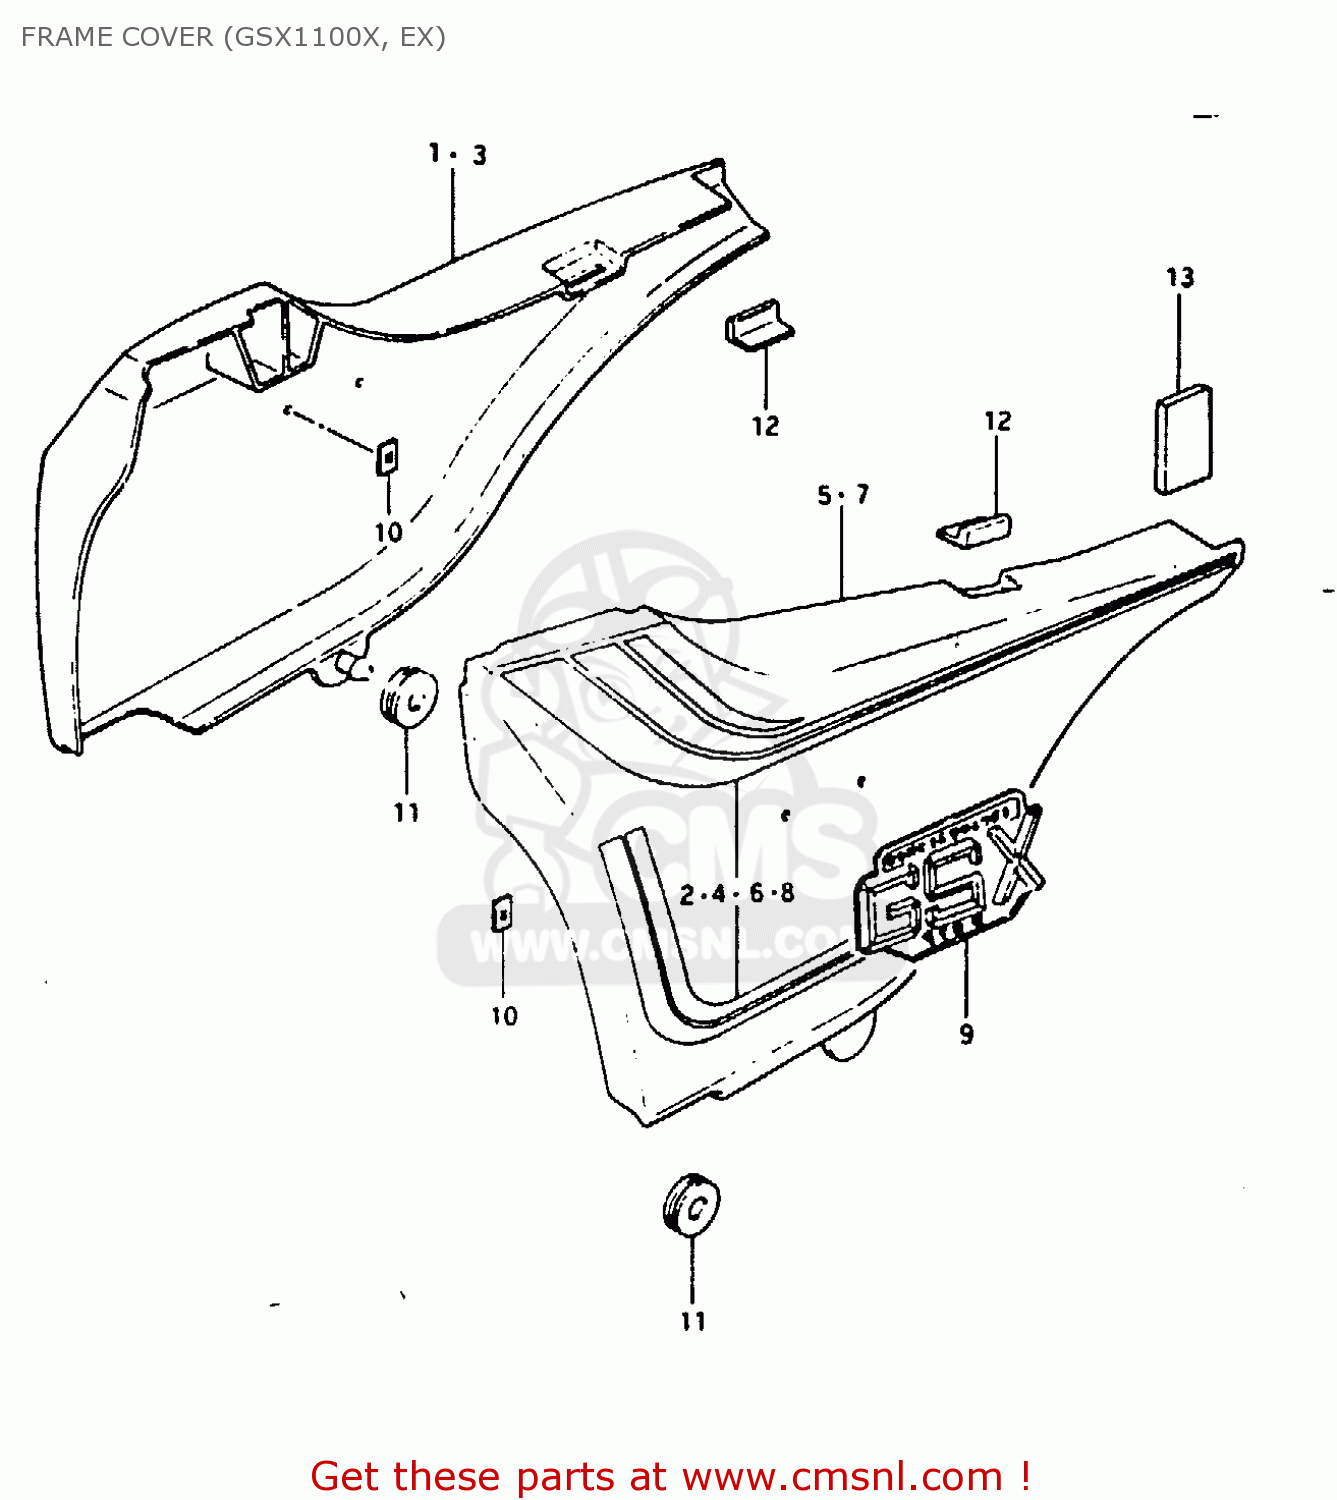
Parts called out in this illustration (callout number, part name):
1	COVER, FRAME RH (RED)
2	TAPE SET, RH
3	COVER, FRAME RH (RED)
4	TAPE, RH
5	COVER, FRAME LH (BLUE)
6	TAPE SET, LH
7	COVER, FRAME LH (RED)
8	TAPE, LH
9	EMBLEM,FRAME COVER
10	NUT
11	CUSHION
12	CUSHION,FRAME COVER
13	RUBBER,FRAME COVER
